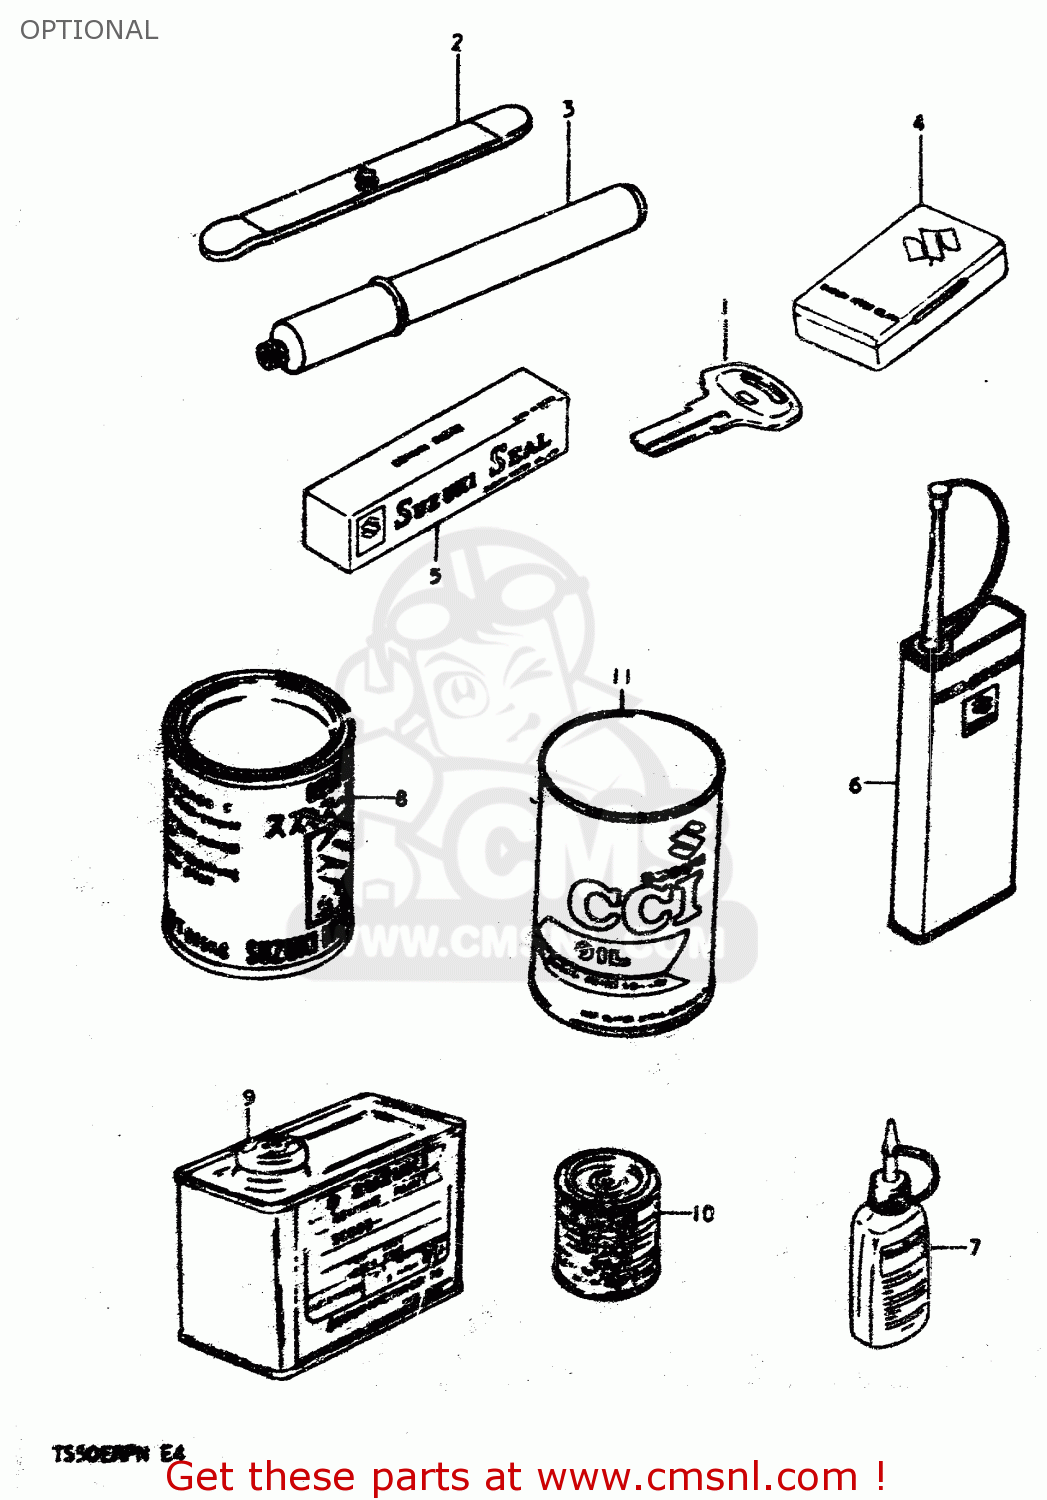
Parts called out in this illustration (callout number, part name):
1	KEY,BLANK
2	LEVER,TIRE
3	INFLATOR, AIR
4	TUBE REPARING TOOL
5	GASKET, LIQUID
6	THREAD LOCK NO.1401 CLEAR 200G
7	THREAD LOCK NO.1303B PURPL 50G
8	GREASE(C)EP2 LITHIUM 150G
9	PAINT (BLACK)
10	PAINT,BLACK
11	CCI OIL
